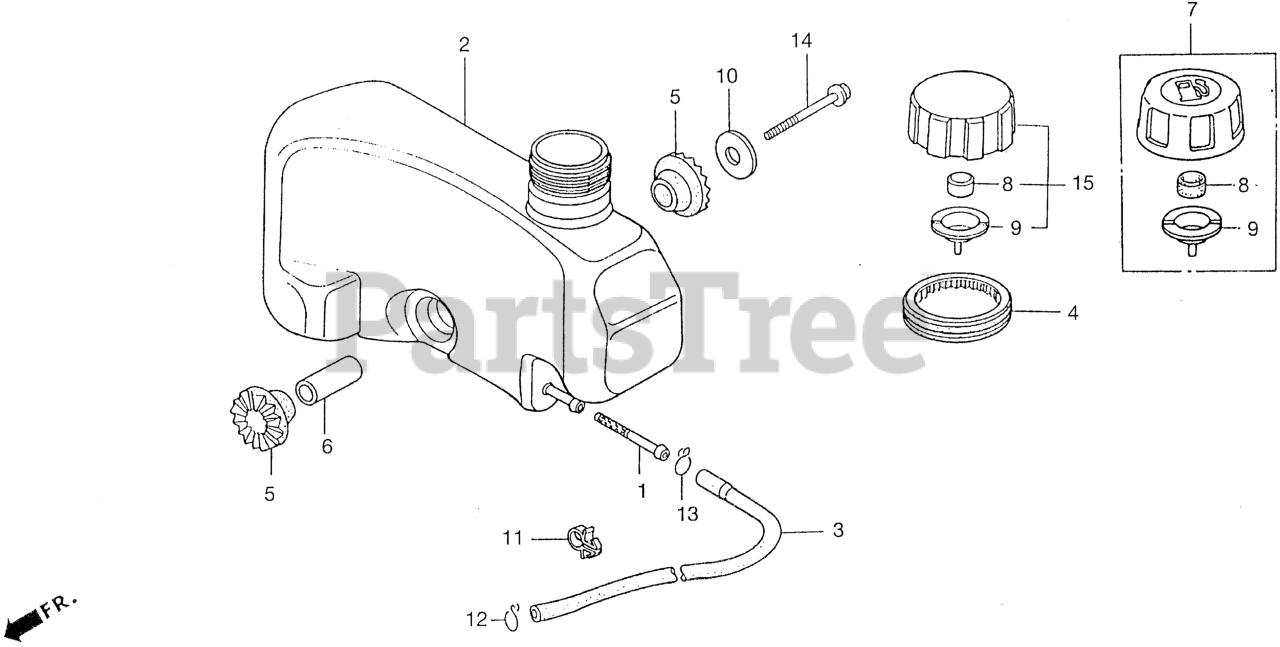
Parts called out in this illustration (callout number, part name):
1	FILTER, FUEL
2	TANK, FUEL
3	TUBE, FUEL
4	RUBBER, TANK MOUNTING
5	RUBBER B, TANK MOUNTING
6	COLLAR, TANK SETTING
7	CAP ASSY., FUEL TANK
8	SPONGE, FUEL CAP BREATHER
9	GASKET, FUEL CAP
10	WASHER, TANK MOUNTING
11	CLIP B, CABLE
12	CLIP, TUBE (B8)
13	CLIP, TUBE (C11)
14	BOLT, FLANGE (8X50)
15	CAP ASSY., FUEL TANK
